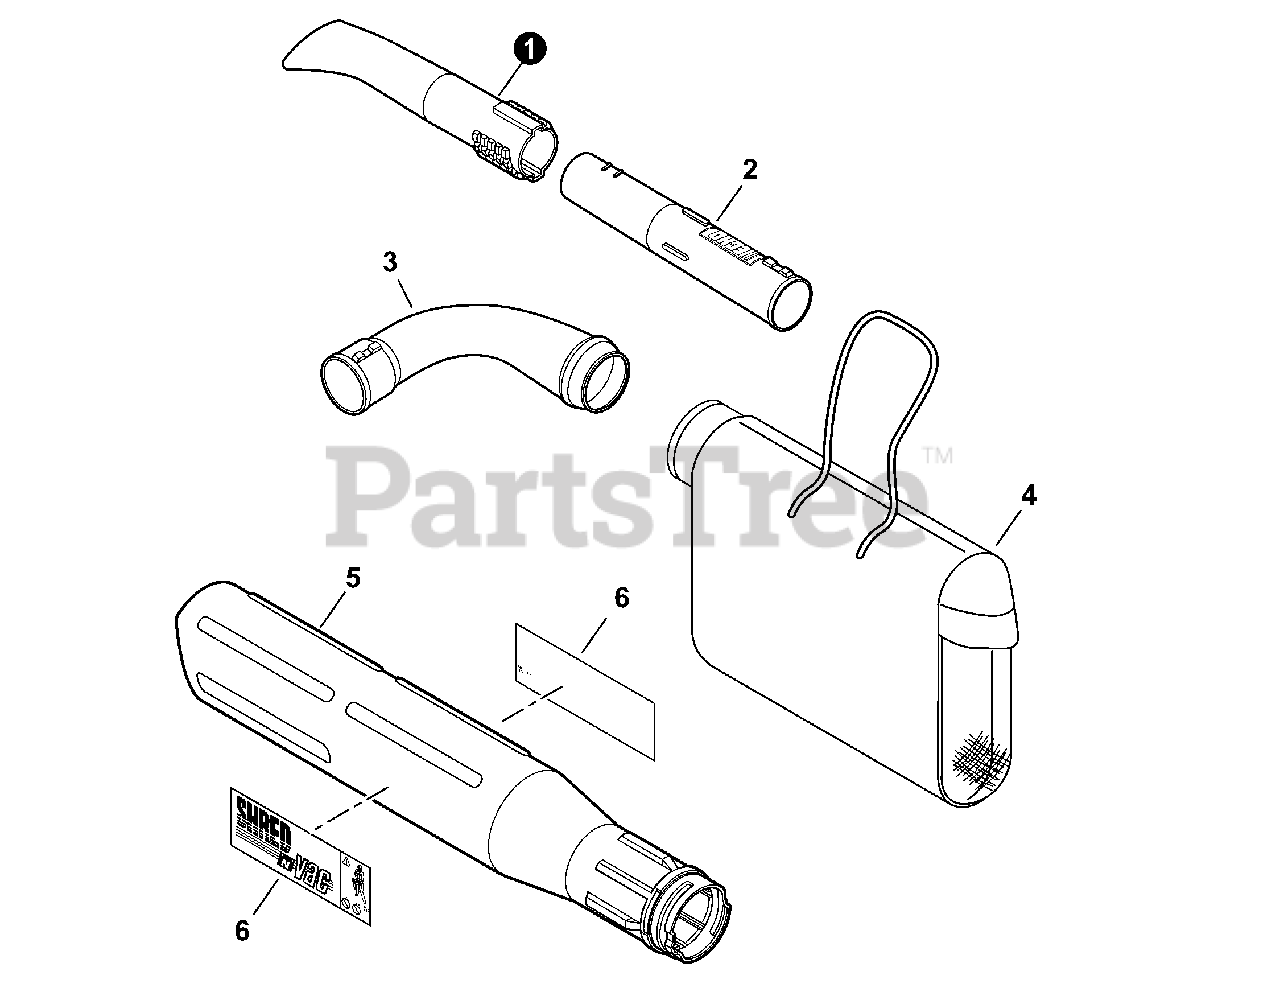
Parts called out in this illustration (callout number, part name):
1	TUBE, BLOWER - FLARED NOZZLE
2	TUBE, BLOWER - STRAIGHT
3	PIPE, MAIN
4	BAG, DEBRIS
5	TUBE, BLOWER - SUCTION
6	LABEL, SHRED'N VAC
